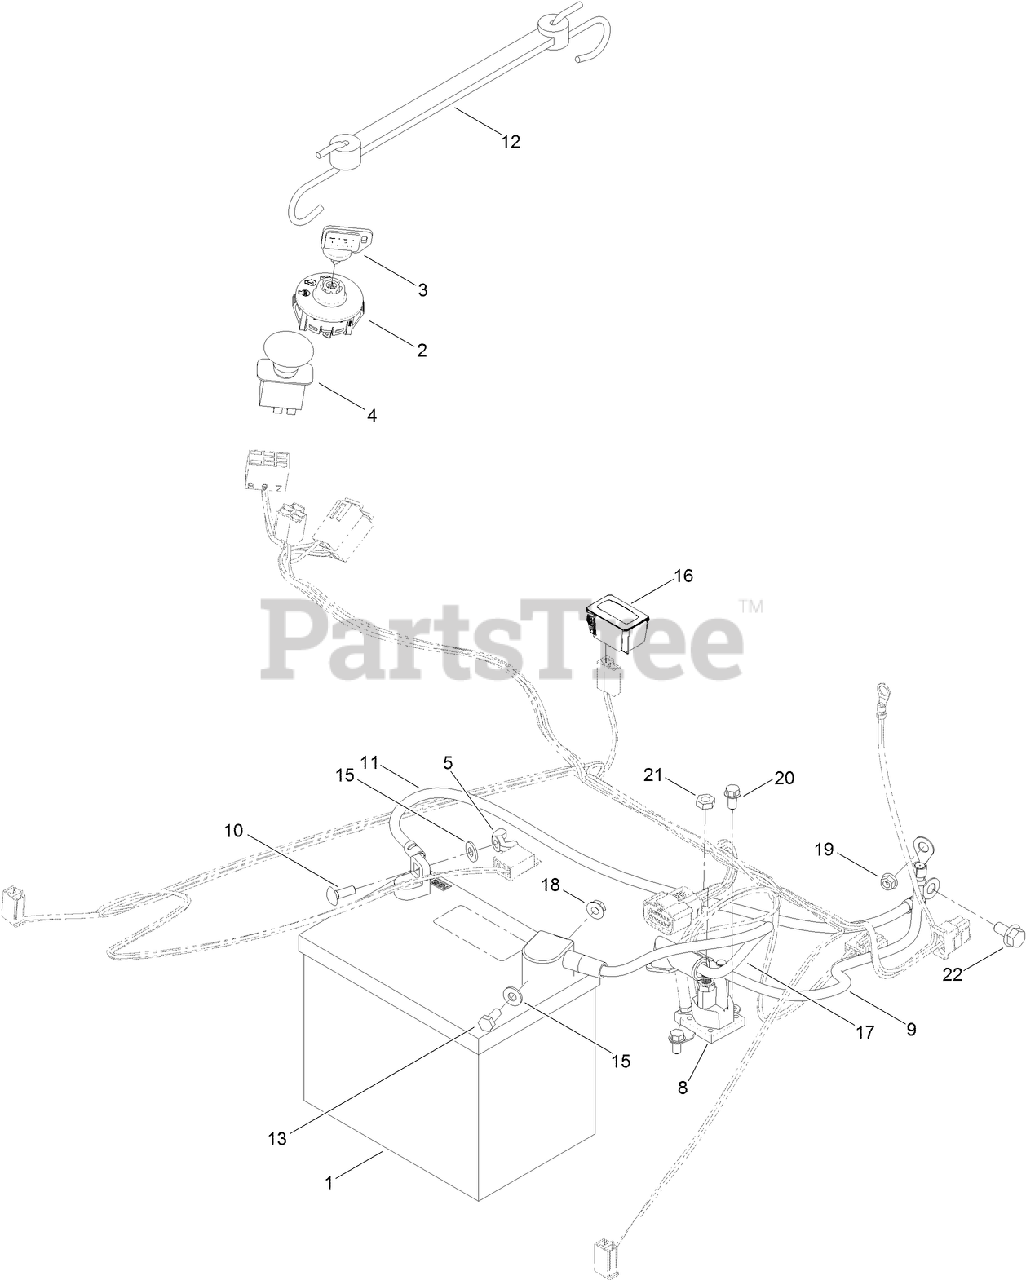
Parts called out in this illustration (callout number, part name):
1	BATTERY
3	KEY-IGNITION
4	SWITCH-PTO
5	NUT-WING
8	SOLENOID
9	CABLE-BATTERY, POSITIVE
10	BOLT-CARR
11	CABLE-BATTERY, BLACK
12	HOLDDOWN-BATTERY
13	SCREW-HH
15	WASHER-FLAT
16	HOURMETER
17	CABLE-BATTERY, RED
18	NUT-HF
19	NUT-HF
20	SCREW-HWH
21	NUT-JAM
22	SCREW-HHF
